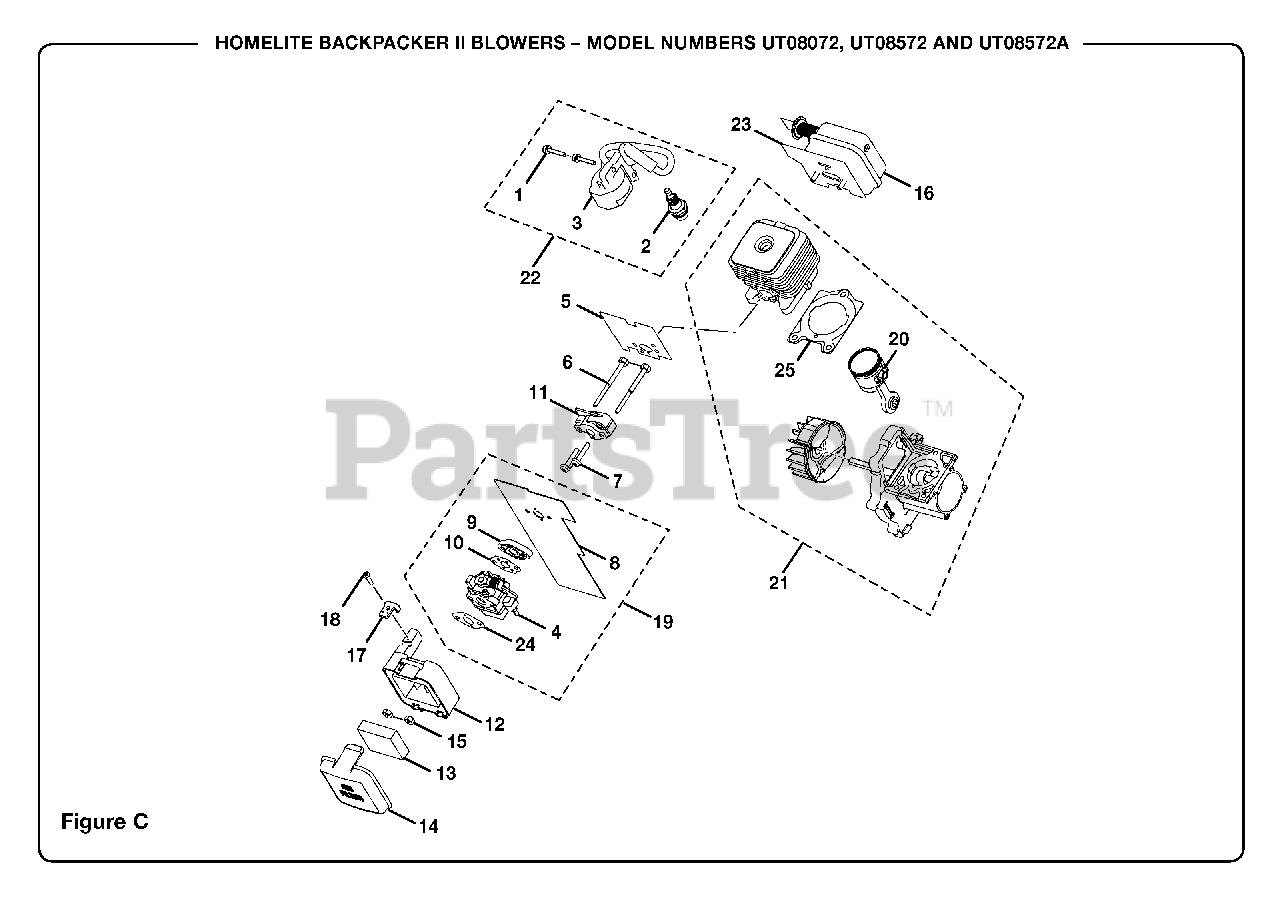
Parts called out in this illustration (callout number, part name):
1	SCREW THD FORMING
2	SPARK PLUG CHAMPION - RCJ-6Y
3	IGNITION MODULE
4	CARBURETOR
5	HEAT DAM GASKET
6	CARBURETOR MOUNTING BOLT
7	SCREW (10-24 x 1.11 PAN HD.).
8	CARBURETOR GASKET
9	SPACER
10	GASKET
11	HEAT DAM
12	AIR FILTER BOX
13	AIR FILTER
14	AIR FILTER COVER
15	HEX NUT (10-24)
16	MUFFLER
17	THROTTLE CABLE CLIP
18	SCREW-FILTER BOX
19	CARBURETOR KIT
20	PISTON ASSEMBLY KIT
21	SHORT BLOCK ASSEMBLY
22	IGNITION KIT
23	MUFFLER GASKET
24	CARBURETOR GASKET
25	CYLINDER GASKET
